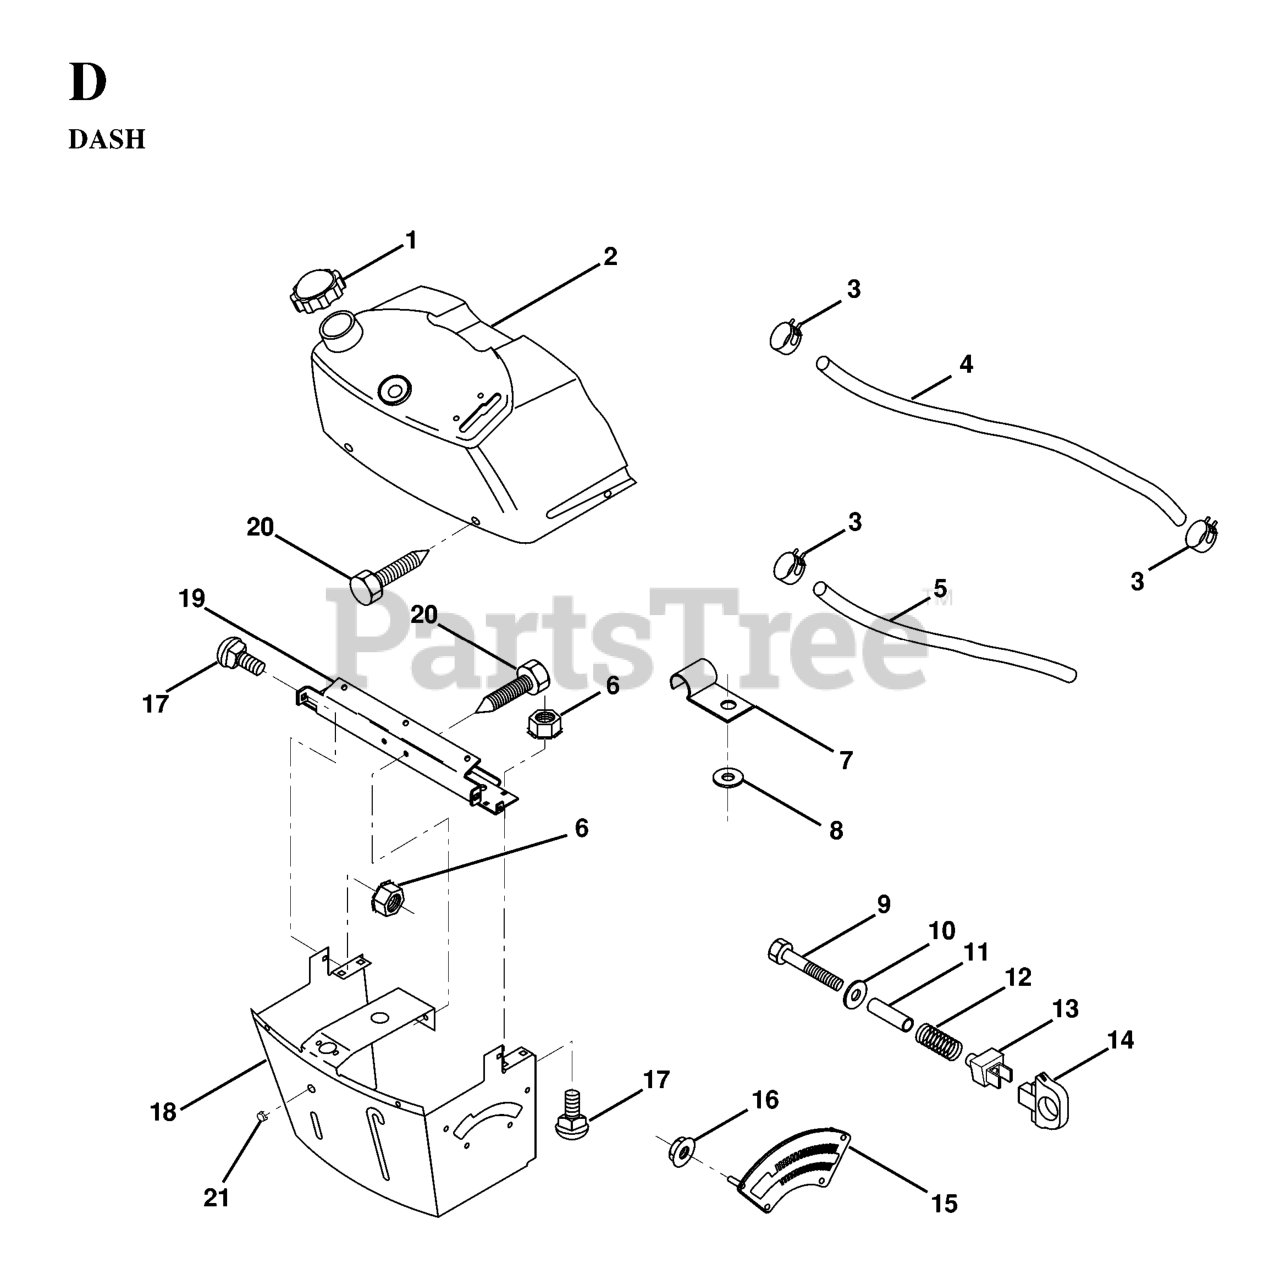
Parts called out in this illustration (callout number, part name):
1	CAP.FUEL.GREY
2	TANK ASM DASH LR
3	HOSE CLAMP
4	FUEL LINE
5	FUEL LINE T
6	Nut, Keps Blk Hex 1/4-20 UNC
7	CLIP T
9	BOLT HEX FIN 1/4-20X1 3/4
10	WASHER
11	SPACER SPLIT
12	SPRING.COMPRESSION
13	KNOB HGT RETAINER
15	ADJUSTER QUAD
16	NUT.PUSH.3/16
18	SUPT ASSY DASH
19	CROSS BRACE
